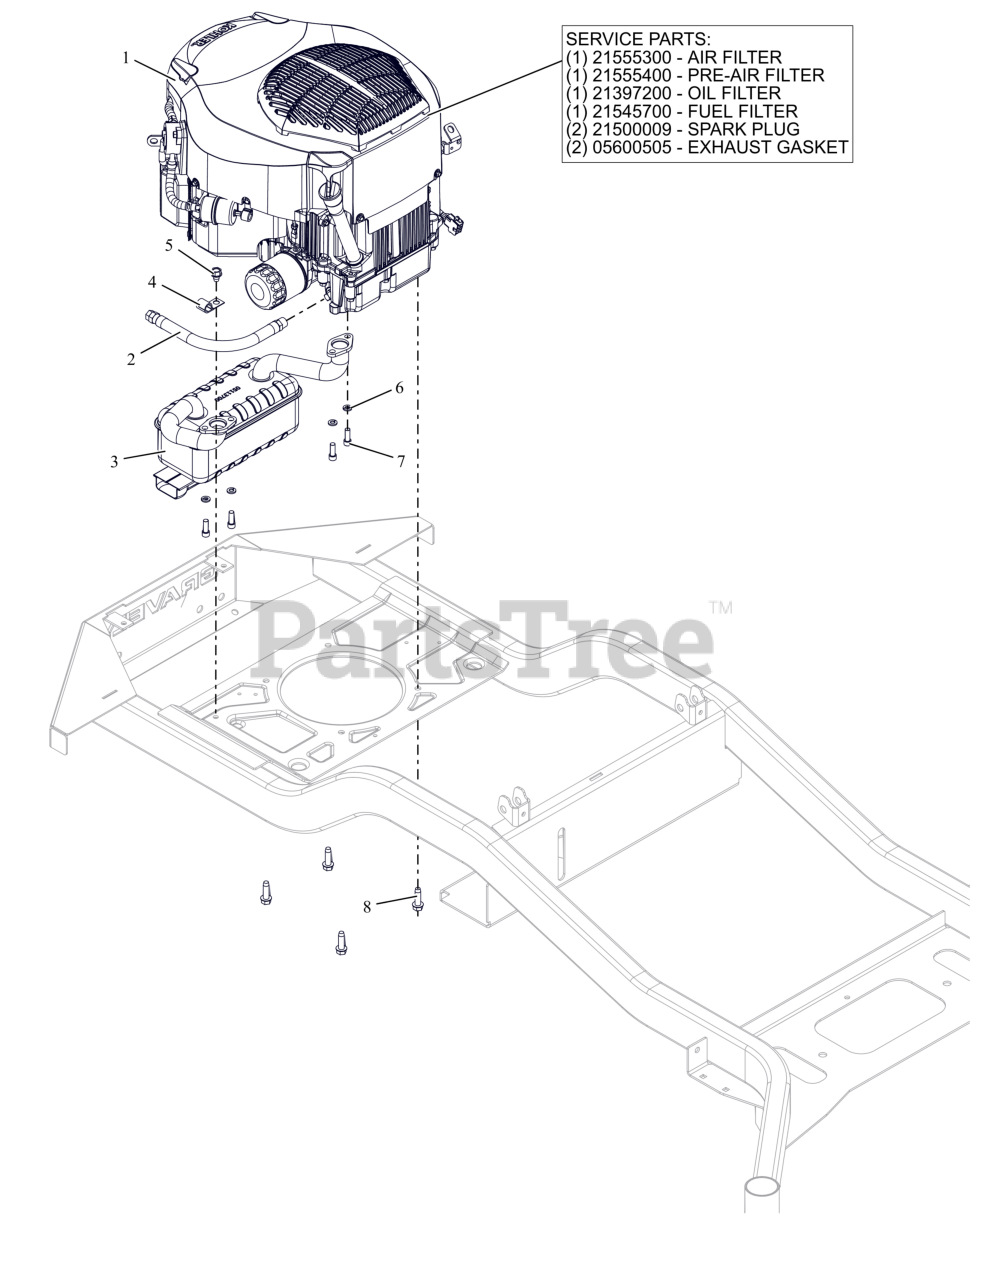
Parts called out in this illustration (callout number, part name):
1	ENGINE, KOHLER - KT745
1	AIR FILTER, KOHLER
1	PRE CLEANER, KOHLER
1	FILTER, OIL - KOH CV20
1	FILTER-FUEL KOHLER COURAGE PRO
1	PLUG, SPARK KOHLER
1	GASKET, MUFFLER KOHLER TWIN
2	HOSE, OIL DRAIN
3	MUFFLER, KOHLER
5	SCR,TAP .375-16X.50 HWH TR ZCC
6	WSHR,LK-REG .312X.078 ZCC
7	SCR, SKH .312-18X.875 GR8 ZCC
8	SCR,TAP .375-16X1.25HWH TR ZCC
